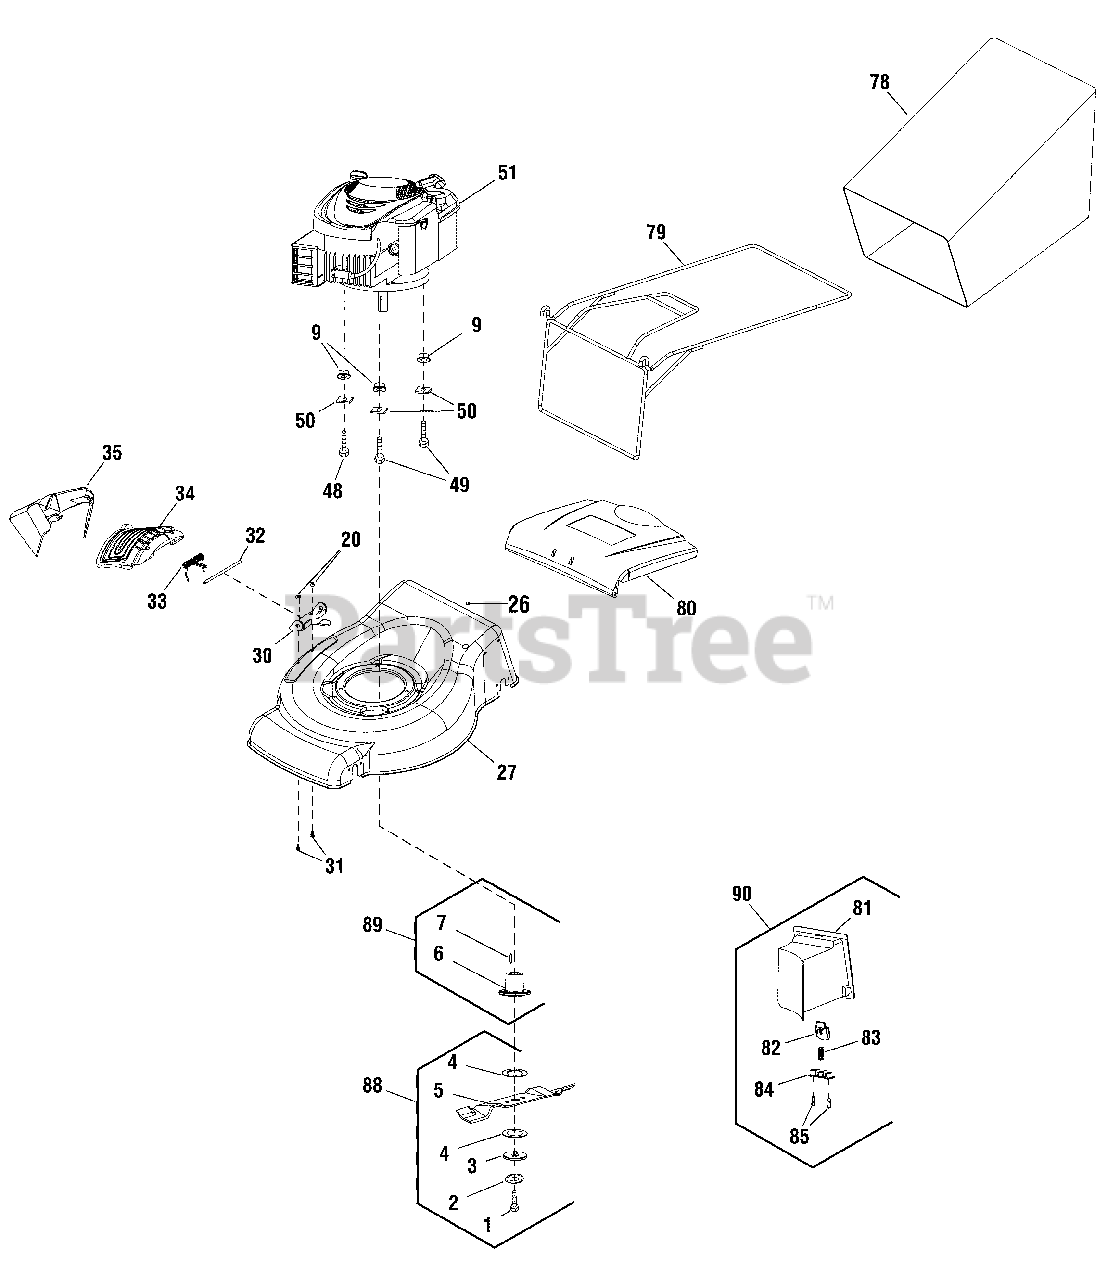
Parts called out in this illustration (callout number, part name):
1	BOLT, Blade
3	PLATE, Blade Support
4	PLATE, Blade
6	SUPPORT, Blade
9	* NUT, Hex Lock
20	* NUT, Hex Lock
26	GROMMET
30	BRACKET, Side Discharge
31	BOLT, Cup Head Square Neck
34	COVER, Side Discharge
35	DEFLECTOR, Discharge
48	* BOLT, Hex
49	* BOLT, Hex
50	WASHER, Square
51	** ENGINE, Briggs & Stratton 650 Series
78	BAG, Grass
80	COVER, Rear
81	MULCH PLUG
82	KNOB, Locking
84	BRACKET, Mulch Plug
88	KIT, Blade
89	KIT, Blade Adapter
90	KIT, Muffler Plug Assembly
